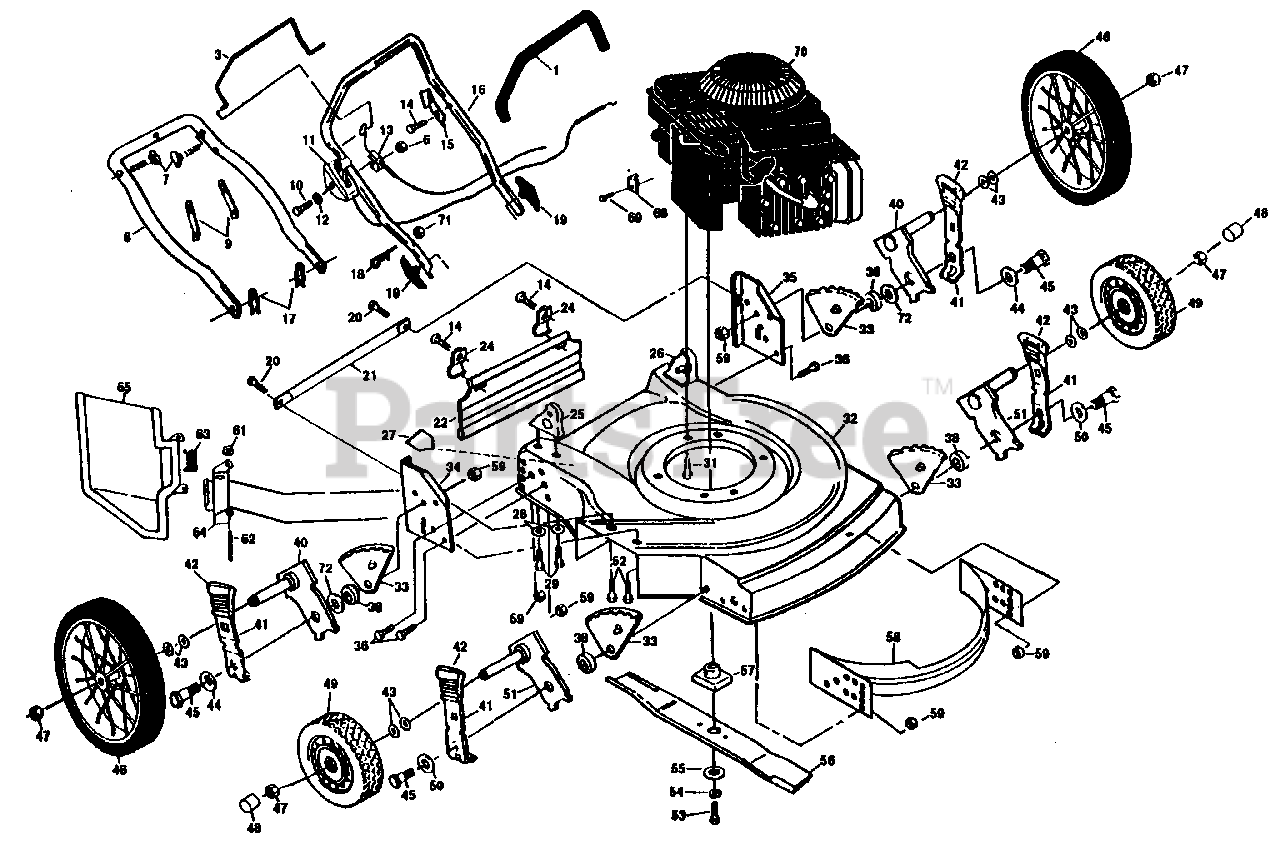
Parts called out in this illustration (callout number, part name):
1	Handle Grip (AYP part number)
3	Control Bar (AYP part number)
6	Locknut 1/4-20 (AYP part number)
7	Handle Bolt 5/16-18 x 1-3/4 (AYP part number)
8	Lower Handle (AYP part number)
9	Wire Tie (AYP part number)
10	Machine Screw 1/4-20 x 2-1/8 (AYP part number)
11	Throttle Control
12	Washer (AYP part number)
13	Engine Zone Control Cable
14	Hex Washer Head Screw #10-24 x 1/2 (AYP part number)
15	Up-Stop Bracket (AYP part number)
16	Upper Handle (AYP part number)
17	Hairpin Cotter (AYP part number)
18	Rope Guide
19	Handle Knob (AYP part number)
20	Self-tapping Screw 1/4-20 x 1/2 (AYP part number)
21	Support Rod (AYP part number)
22	Rear Skirt (AYP part number)
24	Skirt Bracket (AYP part number)
25	Handle Bracket Assembly (Right) (AYP part number)
26	Handle Bracket Assembly (Left) (AYP part number)
27	Danger Decal (AYP part number)
28	Washer (AYP part number)
29	Thread Cutting Screw 5/16-18 x 1-3/4 (AYP part number)
31	Thread Rolling Screw 3/8-16 x 1 (AYP part number)
32	Lawn Mower Housing (Includes Key No. 27 & 58)
33	Wheel Adjusting Bracket (AYP part number)
34	Wheel Support Bracket (Right) (AYP part number)
35	Wheel Support Bracket (Left) (AYP part number)
36	Hex Head Bolt 3/8-16 x 3/4 (AYP part number)
38	Spacer (AYP part number)
40	Axle Arm Assembly (Rear) (AYP part number)
41	Selector Spring (AYP part number)
42	Selector Knob
43	Washer (AYP part number)
44	Washer (AYP part number)
45	Shoulder Bolt 3/8-16 (AYP part number)
46	Wheel & Tire Assembly (AYP part number)
47	Locknut (AYP part number)
48	Hubcap (AYP part number)
49	Wheel & Tire Assembly
50	Washer (AYP part number)
51	Axle Arm Assembly (Front) (AYP part number)
52	Hex Screw W/Sems 1/4-20 3/8 (AYP part number)
53	Hex Head Screw 3/8-24 x 1-3/8 Gr. 8
54	Helical Washer 3/8 (AYP part number)
55	Hardened Washer (AYP part number)
56	22" Blade
57	Blade Adapter (AYP part number)
58	Front Baffle & Rear (AYP part number)
59	Locknut 3/8-16 (AYP part number)
61	Speed-Nut (AYP part number)
62	Hinge Rod (AYP part number)
63	Torsion Spring (AYP part number)
64	Housing Bracket Assembly (AYP part number)
65	Discharge Guard
68	Cable Clamp (AYP part number)
69	Thread Rolling Screw #10-32 x 5/8 (AYP part number)
71	Locknut, Keps 1/4-20 (AYP part number)
72	Flat Washer 3/8 (AYP part number)
